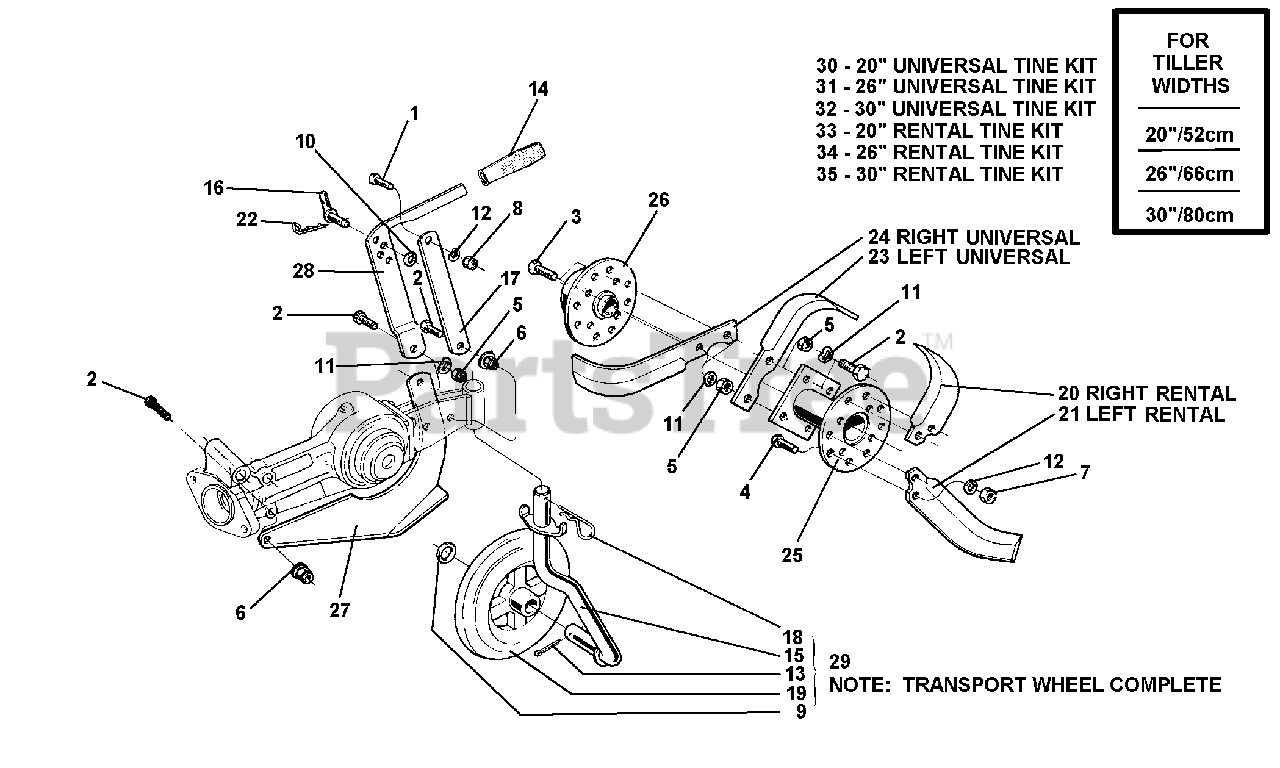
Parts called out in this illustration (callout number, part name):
1	SCREW TE M10 X 25
2	SCREW M8 X 25
3	SCREW M8 X 35
4	SCREW TE M10 X 25 UNI 5739-8G
5	NUT, SELF LOCKING M8
7	NUT, SELF LOCKING M10
8	NUT, SELF LOCKING M10 LOW
10	WASHER P10.5 X 18
11	WASHER, LOCK 8.4
12	WASHER, LOCK 10.5
13	PIN, COTTER A 4 X 30 UNI 1336
15	WHEEL SUPPORT PIN
16	ADJUSTMENT PIN
17	ROTARY HOE HOOD ROD
19	RUBBER WHEEL D 22
20	RENTAL RIGHT KNIFE
21	RENTAL LEFT KNIFE
23	UNIVERSAL LEFT KNIFE
24	UNVERSAL RIGHT KNIFE
25	SPACER KNIVES
26	BLADE HOLDER FLANGE D 25
27	CENTRAL KNIFE
29	TRANSPORT WHEEL ASSEMBLY
30	20" UNIVERSAL TINE KIT
31	26" UNIVERSAL TINE KIT
32	30" UNIVERSAL TINE KIT
33	20" RENTAL TINE KIT
34	26" RENTAL TINE KIT
35	30" RENTAL TINE KIT
